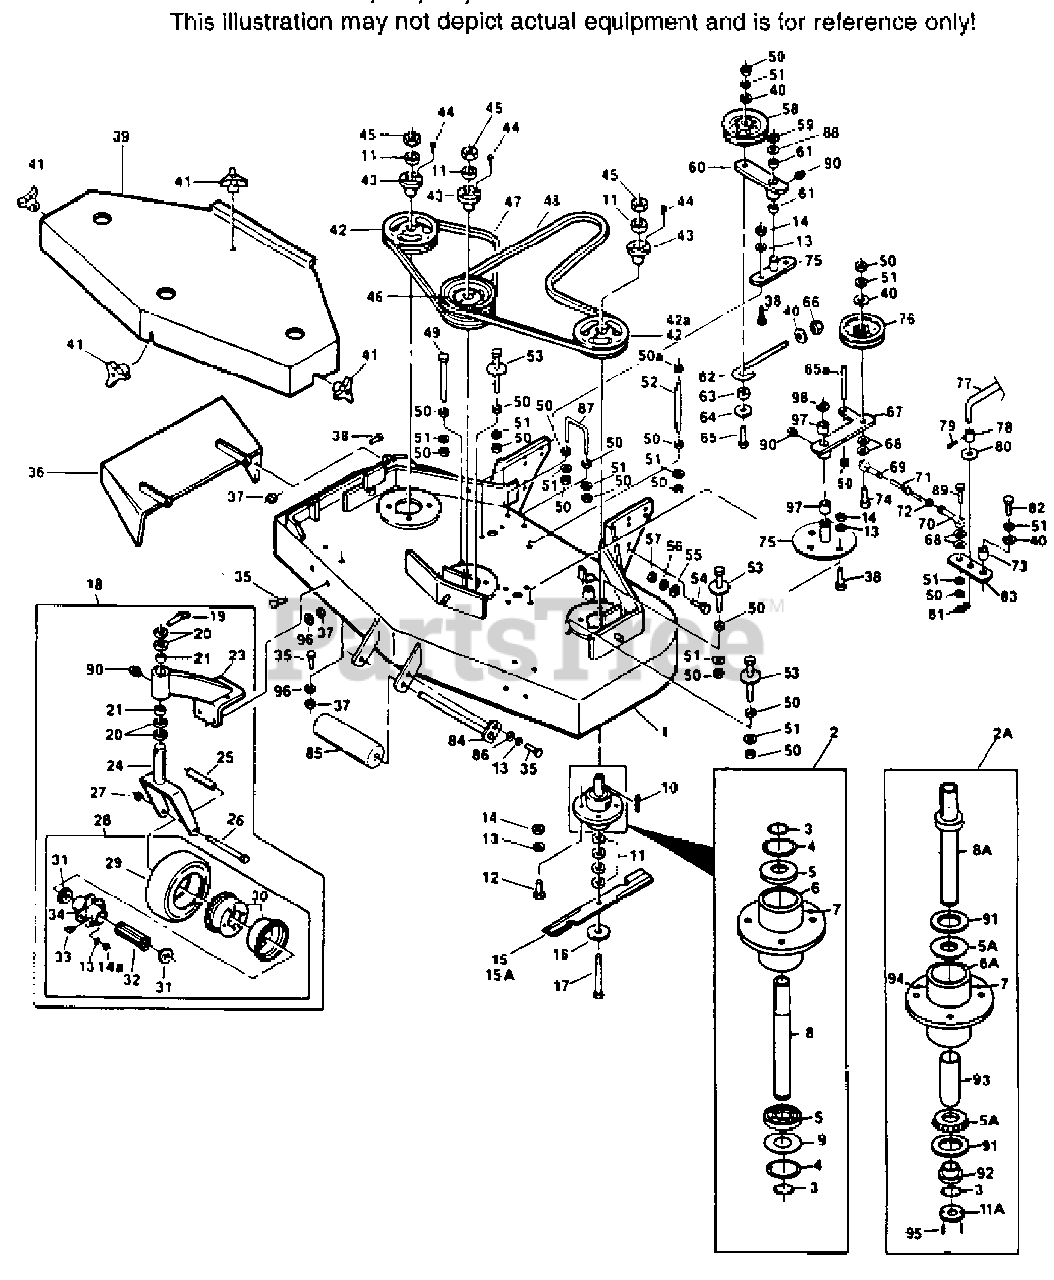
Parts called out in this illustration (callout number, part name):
1	CUTTER DECK(INCLUDES DECALS)
2	CUTTER SPINDLE ASSY. BALL BEARING
2A	SPINDLE ASSEMBLY, TAPERED BEARING
3	RETAINING RING, 1" EXT.-INVERTED
4	RETAINING RING, 2-7/16" INT.BASIC
5	BEARING, CUTTER SPINDLE
5A	TAPERED BEARING
6	SPINDLE HOUSING
6A	SPINDLE HOUSING, TAPERED BEARING
7	GREASE FITTING STR. 5/16 SERR.
8	SPINDLE, CUTTER BLADE
8A	SPINDLE SHAFT, TAPPER BEARING
9	WASHER, 1-5/16 X 2-7/16 X 16 GA.
10	KEY, 1/4 X 1/4 X 2
11	SPACER, CUTTER BLADE
11A	SPACER, CUTTER BLADE, TAPERED
15	CUTTER BLADE 16-1/2"
15A	CUTTER BLADE 16-1/2" HI LIFT
16	FLAT WASHER, 5/8" W
17	HEX HD. BOLT, 5/8-11 X 9-1/2"
18	CASTER ASSY, COMP.(INCL. 19-28)
19	QUICK PIN
20	SPACER, CASTER YOKE, 1/2" THICK
21	BRONZE BEARING
23	SUPPORT ASSY.(INCL. 21-90)
24	CASTER YOKE
25	SLEEVE, CASTER WHEEL BEARING
26	HEX HD BOLT, 1/2-13 X 5-1/2"
28	WHEEL ASSY.(INCL. 13-14, 29-34)
29	TIRE ONLY, CASTER WHEEL
29	INNER TUBE ONLY, CASTER WHEEL
30	RIM PAIR, CASTER WHEEL
31	RETAINER, BEARING, CASTER WHEEL
32	ROLLER BEARING, CASTER WHEEL
33	GREASE FITTING 45 DEG., 1/4-28
34	HUB ASSY.(INCL. BOLTS)
36	DISCHARGE CHUTE
37	HEX NUT, 5/16-18 ELASTIC STOP
39	BELT COVER(INCLUDES DECALS)
40	WASHER 25/64 X 15/16 X 12 GA.
41	WING NUT, 3/8-16
42	PULLEY(INCLUDES 43-44)
43	TAPERED HUB
46	PULLEY, DOUBLE(INCLUDES 43-44)
47	BELT, RH BLADE DRIVE
48	BELT, BLADE DRIVE
50A	HEX NUT, 3/8-16, CENTERLOCK
52	SUPPORT, BELT COVER
53	BELT GUIDE
55	WASHER, 15/32 X 59/64 X 16 GA.
58	IDLER PULLEY, "V" GROOVE
59	RETAINING RING, 3/4" EXT. "E"
60	IDLER ARM ASSY.(INCLUDES 82 & 61)
61	BRONZE BEARING
62	J ROD, IDLER PULL
63	SPACER, J PULL ROD
64	WASHER, 3/8 X 1-1/2 X 16 GA.
66	HEX NUT, 3/8-16 ELASTIC STOP
67	IDLER ARM(INCLUDES ITEMS 97, 90)
68	3/8" FLAT WASHER
69	ROD END L.H. THD.(SILVER)
70	ROD END R.H. THD.(GOLD)
71	LINK, TURNBUCKLE
72	3/8"-24 HEX NUT
73	SLEEVE, CAM CLUTCH
75	IDLER PIVOT
76	IDLER PULLEY, BELT CLUTCH
77	BLADE CLUTCH ROD, LOWER
78	SLEEVE, CLUTCH ROD
80	WASHER, 33/64 X 1 X 16 GA.
81	HAIR PIN LARGE
83	CAM LINK
87	BELT GUIDE
89	3/8-16 X 1 1/2" HEX HEAD BOLT
90	GREASE FITTING
91	SEAL
92	SPINDLE BUSHING
93	SLEEVE, CUTTER SPINDLE
94	RELIEF FITTING, CUTTER SPINDLE
97	BRONZE BEARING
98	RETAINING RING 1 1/8 EXT. "E"
